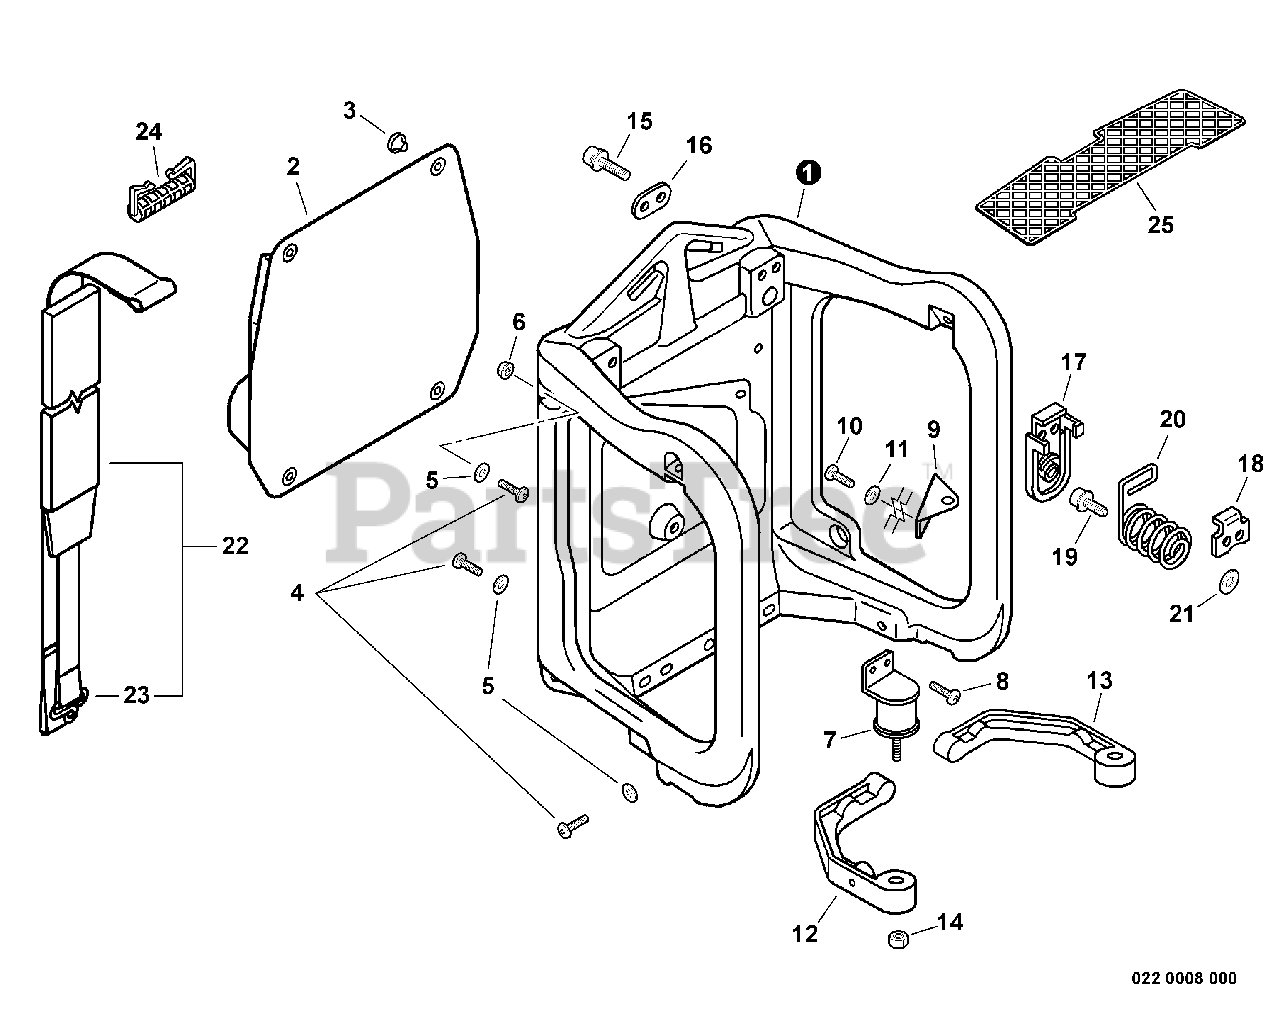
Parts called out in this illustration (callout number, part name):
1	FRAME, BACKPACK
2	CUSHION, BACKPACK
4	SCREW 5×16
5	WASHER 5.5×18×1
6	NUT, FLANGE M5
7	CUSHION
8	SCREW 5×16
9	BRACKET, HANGER
10	BOLT 5×20
11	WASHER 5.5×18×1
12	CONNECTOR, FRAME - LEFT
13	CONNECTOR, FRAME - RIGHT
14	NUT, FLANGE M5
15	SCREW 5×16
16	PLATE, EYE
17	HOLDER, SPRING
18	PLATE, THREADED
19	BOLT 5×20
20	SPRING, COMPRESSION
21	WASHER 5.5×16×2T
22	HARNESS ASSY, BACKPACK
23	RING, HARNESS
24	CLIP, HARNESS
25	COVER, DUST
